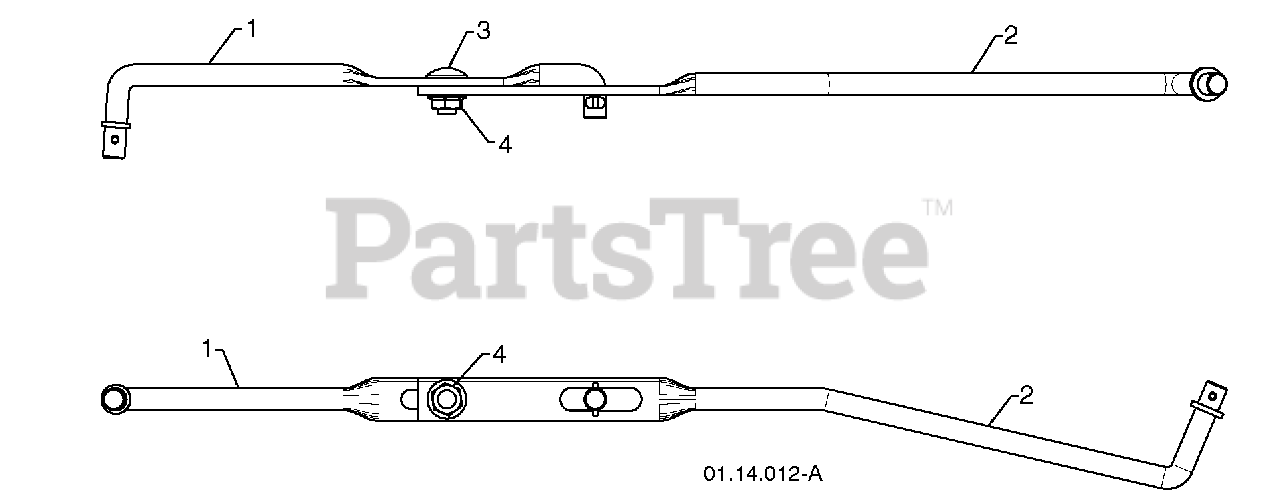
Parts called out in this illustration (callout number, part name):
1	SHIFTER ROD TOP
2	SHIFTER ROD BOTTOM
3	CARRIAGE BOLT 5/16-18 X .75
4	NUT 5/16-18
